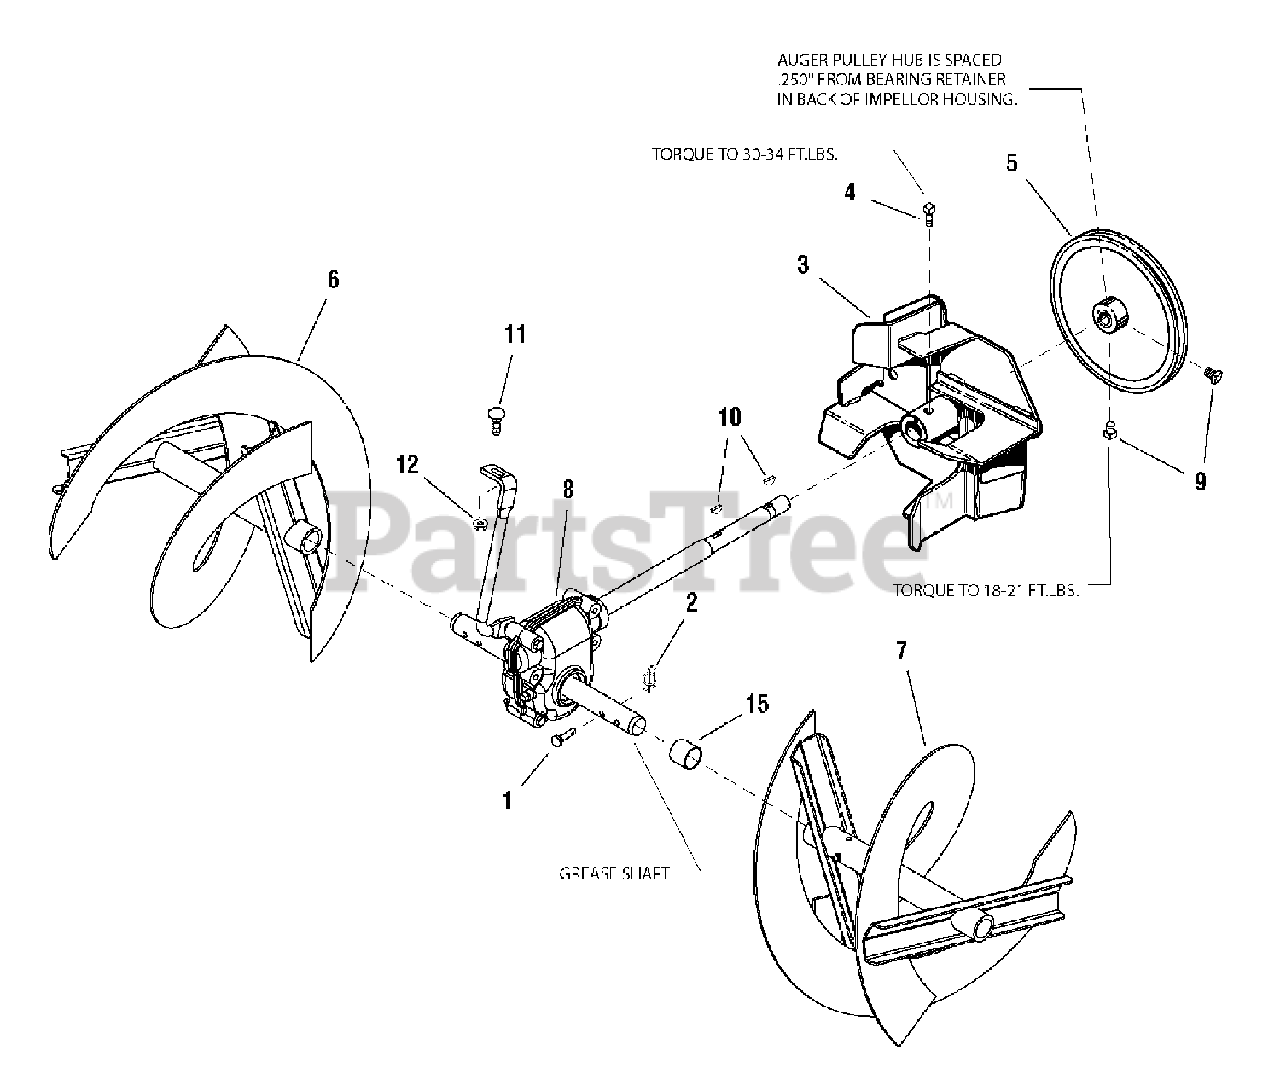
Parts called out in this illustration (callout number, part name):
1	PIN, SHEAR
2	COTTER PIN, 1/4" Self Locking
3	IMPELLER ASSEMBLY, Large Frame Snow
4	SCREW, Set, Square Head Cup Point 3/8-16 x 1/2 G8
5	PULLEY, w/Hub
6	AUGER ASSEMBLY, 24" & 26" R.H.
6	AUGER ASSEMBLY, 28" & 30" R.H.
6	AUGER ASSEMBLY, 32" R.H.
7	AUGER ASSEMBLY, 24" & 26" L.H.
7	AUGER ASSEMBLY, 24" & 30" L.H.
7	AUGER ASSEMBLY, 32" L.H.
8	GEAR BOX ASSEMBLY
9	SCREW, Set, Square Head Cup Point 5/16-18 x 1/2 G8
10	KEY, Woodruff
11	CARRIAGE BOLT, 5/16-18 x 3/4 G5
12	NUT, Hex Flange Whiz Lock, 5/16-18HEX FLANGE 5/16-18
15	TUBE
